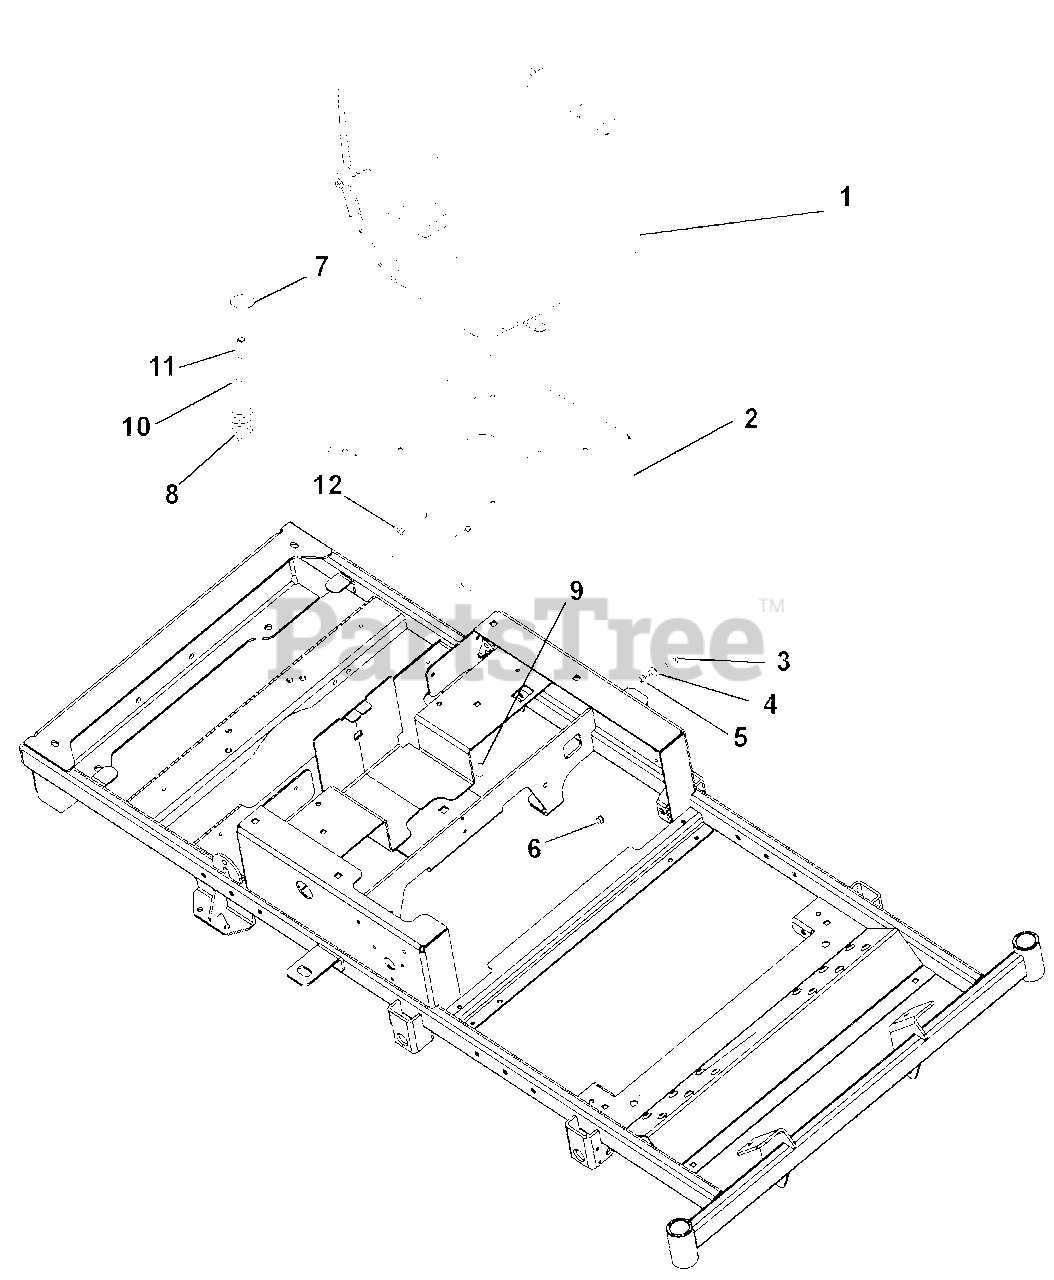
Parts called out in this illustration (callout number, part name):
1	SEAT, MILSCO XB-180
1	SWITCH- SNAP MTG N.O.
2	SEAT PLATE
3	@BLT-HEX .38-16X1.00 GR5 YWZC
4	BSHG-FLG .385X.500X.875X.406
5	WSHR-FL-STL .52X.827X.062 YWZC
6	@NUT-LK-NYL-FLG .38-16 YWZC
7	HUB CAP
8	SPRING, SEAT
9	@BLT-RDHDSQNK .31-18X1.50 G5YZ
10	WSHR-FL-STL .328X.87X.179 YWZC
11	NUT, COUPLING 5/16-18 X 1 3/4
12	@NUT-LK-NYL-FLG .31-18 YWZC
